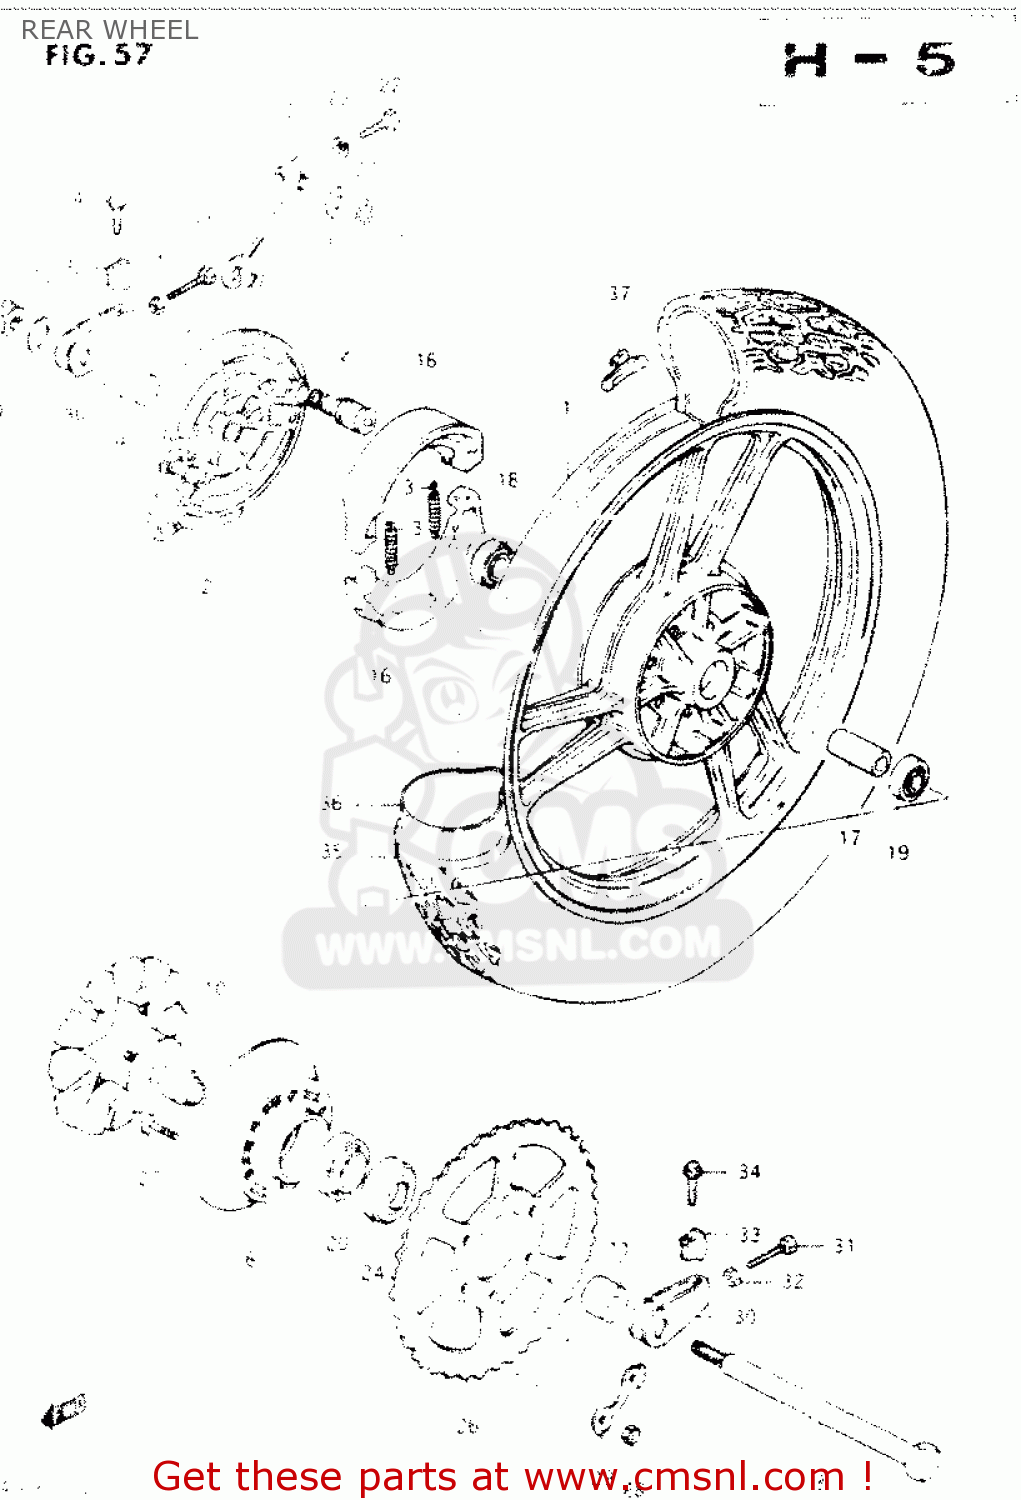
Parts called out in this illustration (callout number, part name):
1	WHEEL, REAR (18X1.85)
2	PANEL,REAR HUB
3	SPRING,BRAKE SHOE
4	CAM,FRONT BRAKE
5	WASHER (15X24X1.6)
6	DRUM,REAR SPROCKET MOUNT
7	ABSORBER,RR HUB SHOCK
8	AXLE,REAR
9	SPACER(17.5X28X44.8)
10	SPACER,REAR HUB BEARING
11	SPACER(17X30.5X22.3)
12	WASHER (17X30X3.2)
13	NUT
14	NUT
15	PIN,COTTER
16	SHOE,BRAKE
17	SPACER (17.6X24X57)
18	BEARING
19	BEARING
20	BEARING
21	LEVER,RR BRAKE CAM
22	BOLT
23	WASHER,LOCK
24	SEAL,OIL(30.5X52X8)
25	O-RING,BOSS
26	SPROCKET,RR
27	BOLT(10X35.5)
28	NUT
29	WASHER
30	ADJUSTER,CHAIN
31	BOLT 8X50
32	NUT
33	SUPPORTER,CHAIN ADJUST
34	BOLT, UPPER
35	TIRE
36	TUBE,INNER
37	BALANCER,WHEEL
